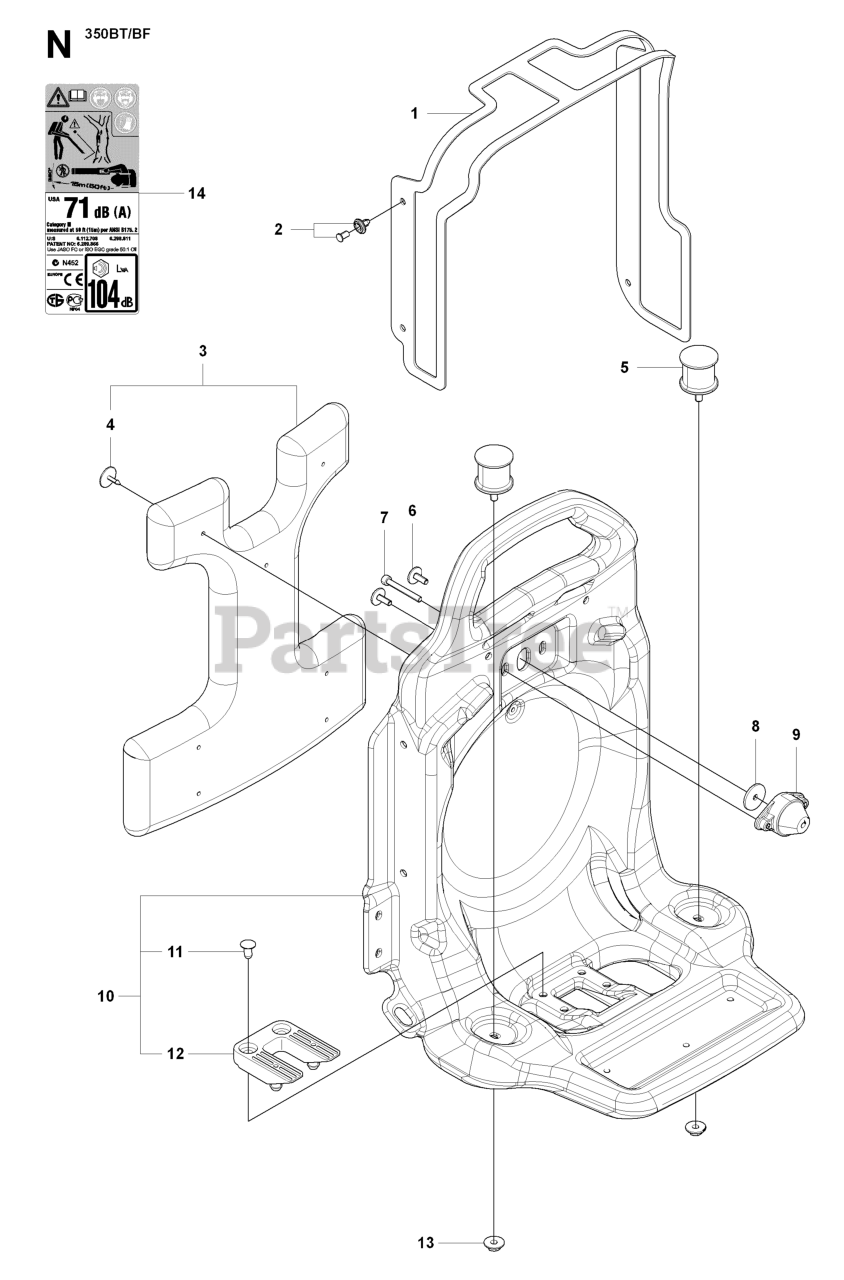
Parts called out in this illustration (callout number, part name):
2	CLIP
3	PAD COMP
4	CLIP
8	WASHER
9	DAMPER UPPER
11	CLIP
14	LABEL CAUTION
